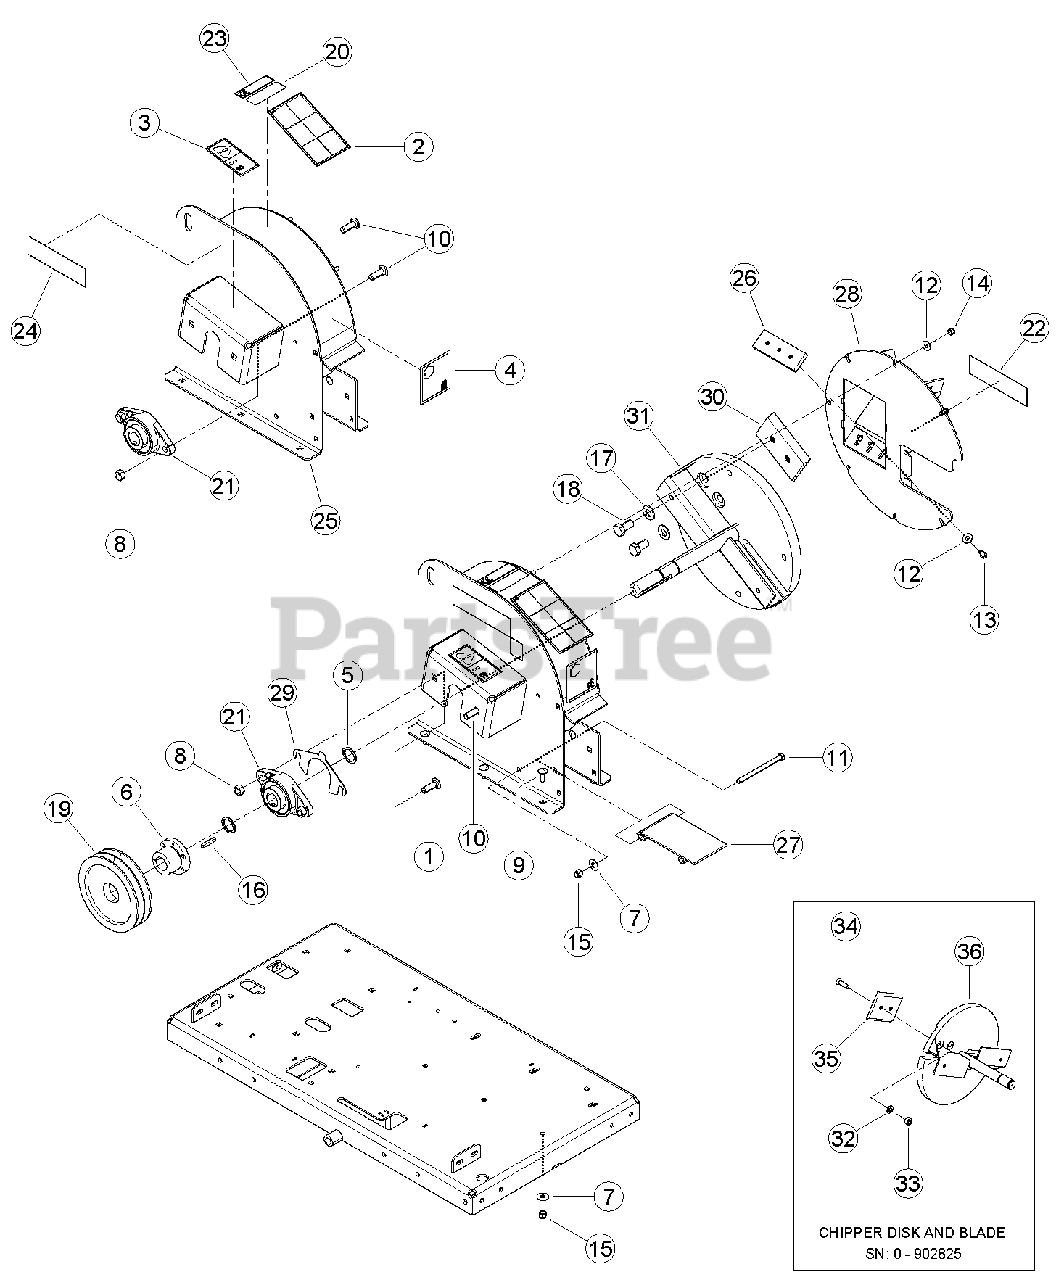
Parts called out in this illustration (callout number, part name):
1	BOLT, 1/2 X 1-3/4 CRG GR5 ZP (CH45342 ONLY)
2	DECAL, OPERATING INSTRUCTIONS ISO
3	DECAL, MAINTENANCE ISO
4	DECAL, 107 DB (CH45342)
4	DECAL, 102 DB (CH45390)
5	SNAP RING, 1-1/4 EXT. HEAVY DUTY
6	BUSHING, SDS 1-1/4"
7	WASHER, 3/8 FLAT ZP
8	NUT, 1/2 CENTERLOCK GRB ZP
9	BOLT, 3/8 X 1 CRG GR5 NC ZP
10	BOLT, 1/2 X 1-1/2 CRG GR5 ZP
11	BOLT, 3/8 X 5 HEX HD GR5 ZP
12	WASHER, 5/16 FLAT ZP
13	BOLT, 5/16 X 5/8 HEX HD GR5 ZP
14	NUT, 5/16 NE NYLOCK ZP
15	NUT, 3/8 NE NYLOCK ZP
16	KEY, 1/4 SQUARE X 1-1/2 LONG PLAIN
17	WASHER, 5/8 SAE HARDENED
18	BOLT, M16 X 2.0 X 30 HEX HD W/PATCH
19	SHEAVE, 2B 6.6 SDS
20	DECAL, SERIAL NUMBER (CH45342 ONLY)
21	BEARING, 1-1/4" DIA 2 BOLT FLANGE
22	DECAL, ECHO BEARCAT 6.82 X 1.90
23	DECAL, 77412S INFORMATION (CE COMPLIANT ONLY)
24	DECAL, MODEL CH45342
24	DECAL, MODEL CH45390
25	WELDMENT, CHIPPER HOUSING
26	ANVIL, CHIPPER
27	WELDMENT, CHIP DEFLECTOR
28	WELDMENT, DISK COVER
29	SHIM, BEARING
30	BLADE, BIG CHIPPER (FOR SERVICE ORDER KIT #76295-00, REPLACEMENT BLADE)
30	KIT, 4-1/2 CHIPPER BLADE KIT
31	WELDMENT, 4-1/2 CHIPPER DISK
32	WASHER, 1/2 HI-STRENGTH SAE ZP
33	LOCKNUT, 1/2-13 SECURITY
34	SCREW, 1/2 X 1-3/4 FLHD CAP
35	BLADE, BIG CHIPPER (FOR SERVICE ORDER KIT #74744-00, REPLACEMENT BLADE)
35	KIT, CHIPPER BLADE KIT
36	WELDMENT, 4-1/2 PTO DISK
